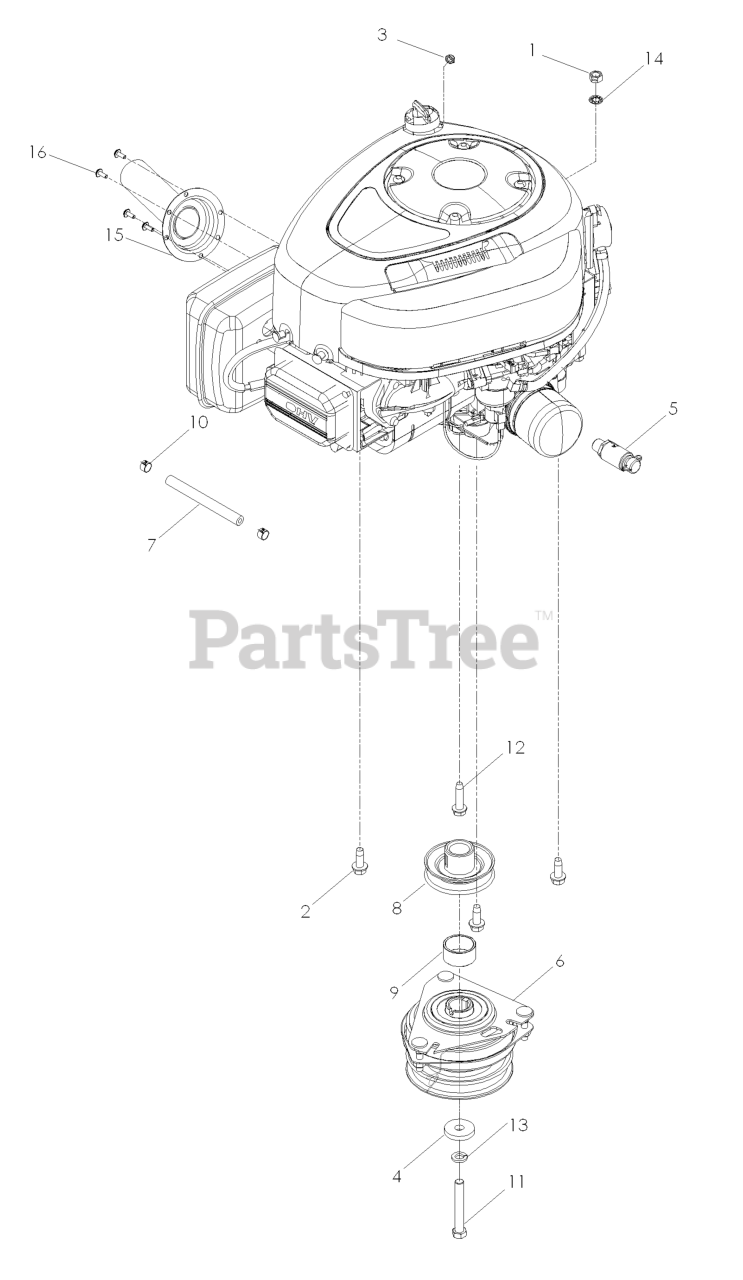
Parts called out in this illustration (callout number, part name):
1	NUT 3/8C CENTERBLOCK
2	BOLT 3/8-16 X 1.0
3	JAM NUT 1/4C (2 2 PW01)
4	CLUTCH, WASHER
5	OIL DRAIN FITTING
6	CLUTCH 90 FT/LB OGURA
7	FUEL LINE 5"
8	PULLEY, ENGINE
9	SPACER, ENGINE - PULLEY
10	HOSE CLAMP
11	HEX SCREW 7/16-20 X 3
12	BOLT 3/8-16 X 1 1/2 ZINC CLEAR
13	WASHER 7/16 LOCK
14	WASHER, 3/8 ITLW ZN
15	MUFFLER EXT.(PAINTED)
16	SCREW, TAP #10-16 X 1/2
